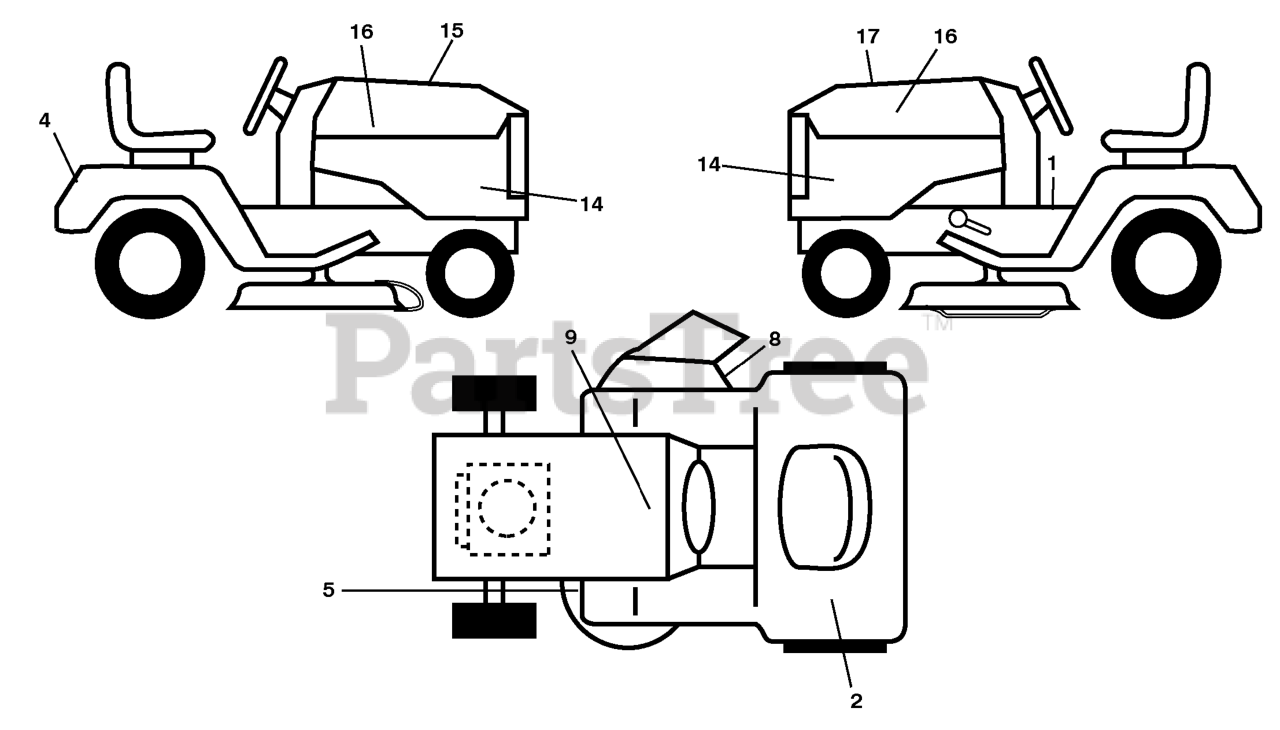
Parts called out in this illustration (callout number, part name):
1	DECAL.WARN.START.INSTRUCTIONS
2	DECAL,ETHANOL E85 WARNING
4	DECAL.FENDER
5	DECAL.MOWER
8	DECAL.MOWER.SCH.48/54
9	DECAL BTRY SYMBOLS
14	DECAL.PNL.SD.LGT2554.KOHL.
15	DECAL.WARNING.CUST.RESP.E85.
16	RP.DECAL.BADGE.170MM.TEXTLOGO
17	DECAL.RPL.KHSV730.TGW.54.0610F
